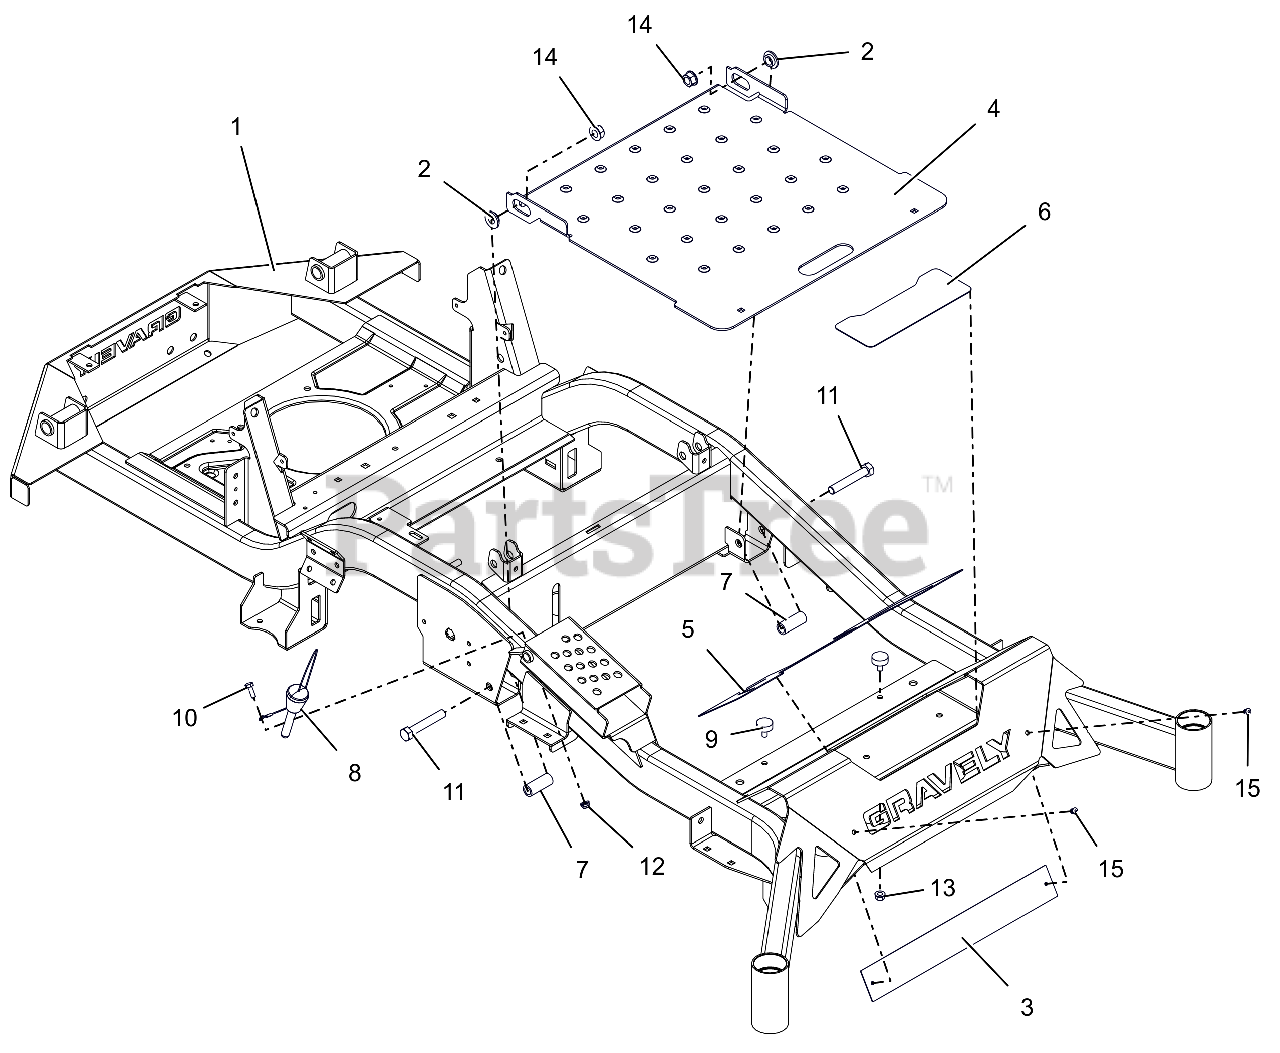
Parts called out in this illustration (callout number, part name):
1	HD 60"FRAME W/SAFETY DECALS
2	BSHG-FLG .515X.750X.310X1.120
3	PLATE, BACK FOOT-REST XL
4	KIT,ACCESS PANEL W/DECALS-RED
5	GRIP, FRONT
6	GRIP, STEP
7	SPACER, .515X.75X1.83
8	PIN, MAGNETIC .50X2.50
9	BUMPER, RUBBER
10	BLT, HEX .25-20X.75 G5 ZCC
11	BLT, HEX .50-13X3.00 G5 ZCC
12	NUT,NYL-FLG .25-20 GF ZCC
13	NUT,SPNLK-FLG .31-18 G5 ZCC
14	NUT-LK-TOP-FLG .500-13 GF ZCC
15	RIVET, .1875 AL/AL .126-.250
